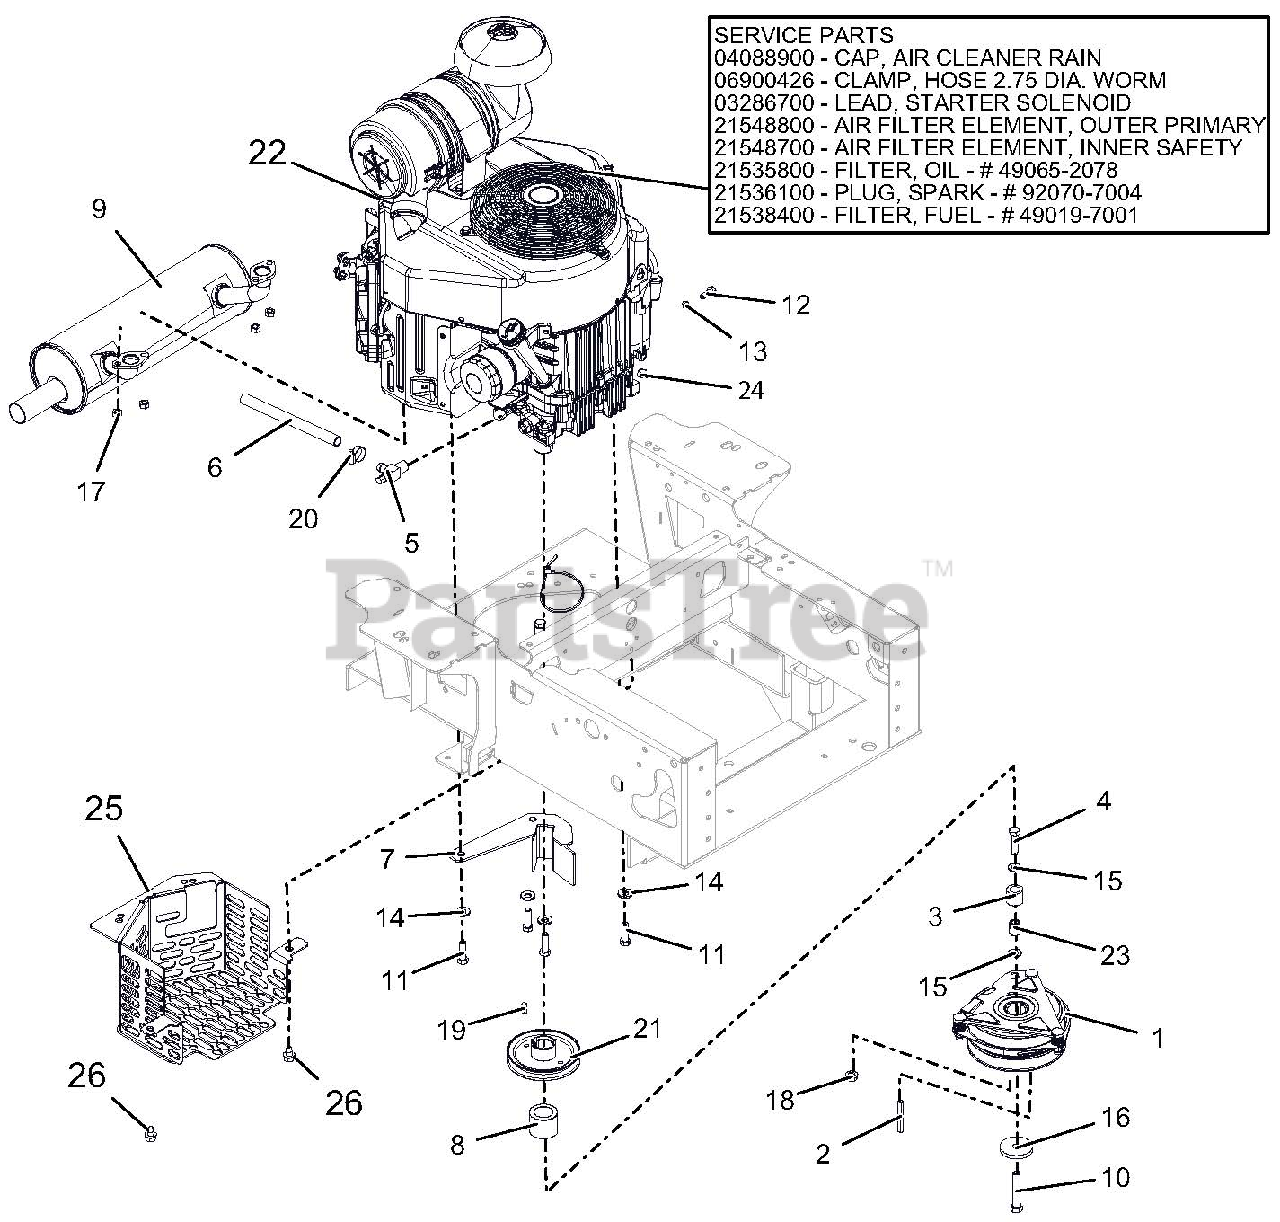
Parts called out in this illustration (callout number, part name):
1	CLUTCH, OGURA GT2.5-FE02
2	KEY, .25X.25X2.25
3	BUMPER, RUBBER .62 X 1.0 X .88 LG
4	BLT-HEX .38-16X1.50 GR5 YWZC
5	DRAIN, 1/2" OIL
6	TUBE, OIL DRAIN 8" CLEAR VINYL
7	WMT, 100I CLUTCH STOP - BLK
8	SPCR, 1.125 X 1.75 X 1.400
9	MUFFLER, KAWASAKI FX24/26 HP
10	BLT-HEX .44-20X2.50 GR5 EP80 YWZC
11	BLT-HEX .38-16X1.25 GR5 YWZC NYTORQ
12	@BLT-HEX M8-1.25X20 YWZC
13	WSHR-LK .31X.078 REG YWZC
14	WSHR, 3/8" SPRING DISC
15	WSHR-FL-STL.406X.812X.065 YWZ
16	WSHR-FL-STL .469X2.00X.25 YWZC
17	NUT-LK-TOP M8-1.25 YWZC
18	NUT, LK-TOP-FLG .38-16 YWZC
19	KEY-SQ .250X.250X.625
20	CLAMP, .88 DIA HOSE
21	PULLEY, 4.50 OD X 1.127 ENGINE-BLACK
22	ENGINE, KAWASAKI FX691
22	CAP, AIR CLEANER RAIN
22	CLAMP, HOSE 2.75 DIA. WORM
22	LEAD, STARTER SOLENOID
22	AIR FILTER ELEMENT, OUTER PRIMARY
22	AIR FILTER ELEMENT, INNER SAFETY
22	FILTER, OIL - # 49065-2078
22	PLUG, SPARK - # 92070-7004
22	FILTER, FUEL - # 49019-7001
23	BUSHING, SLV .391X.622X.950 ST
24	CLAMP, FUEL LINE
25	WLDMT, CLUTCH & BELT GUARD
26	SCR-TAP .38-16X.50 HWH TR YWZ
